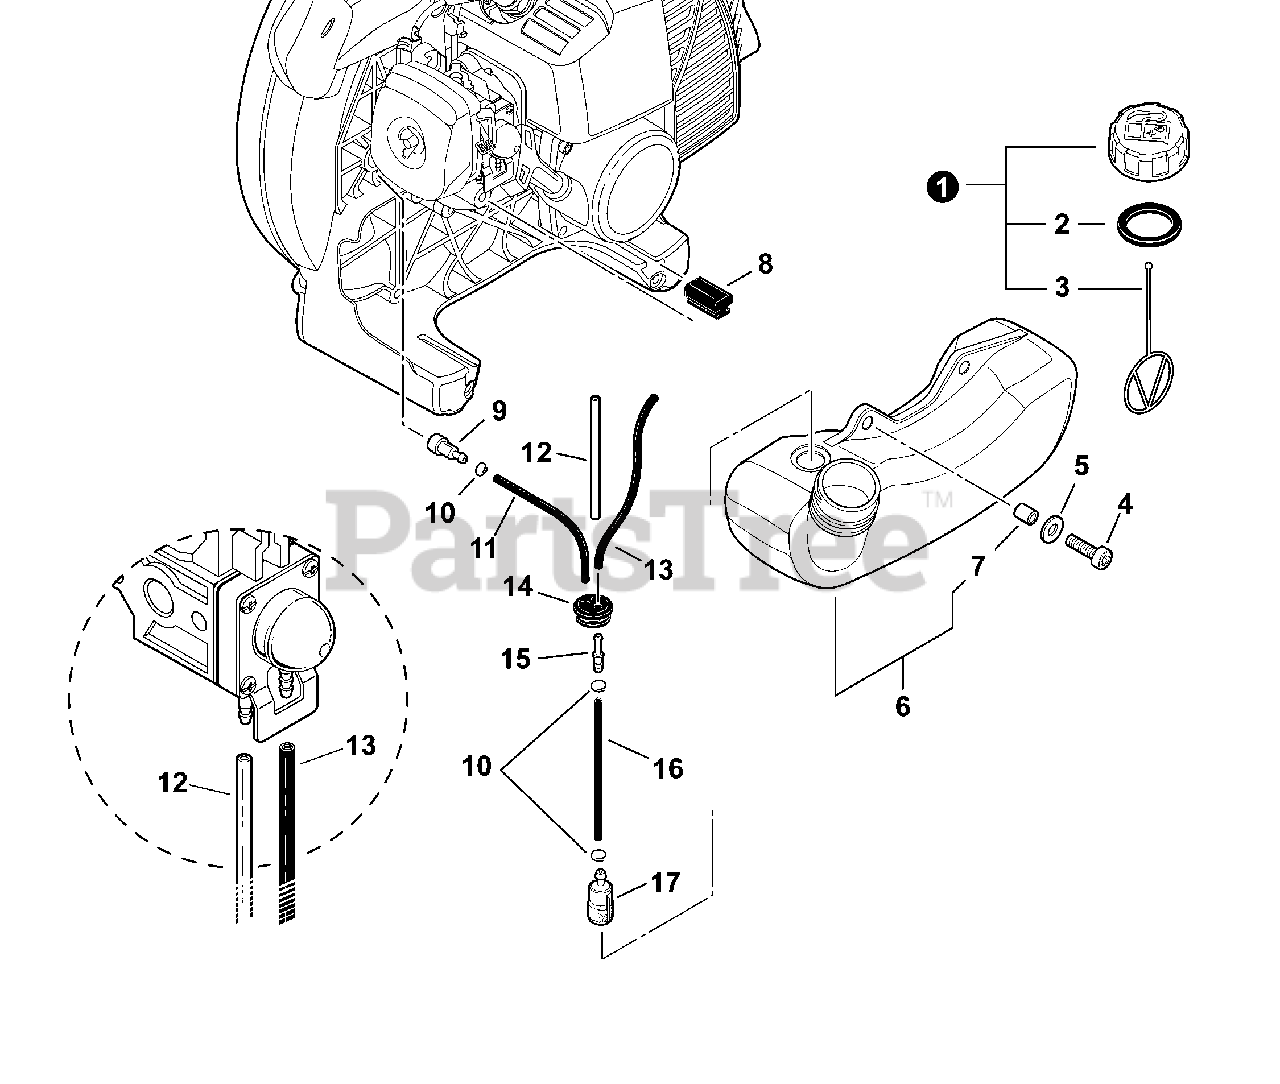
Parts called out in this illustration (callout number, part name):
1	CAP ASSY - ORANGE
2	CONNECTOR, CAP
3	GASKET, CAP
4	SCREW - 5×16
5	WASHER - 5
6	FUEL TANK ASSY
9	VENT, FUEL TANK
10	CLIP - 6
11	PIPE - 3×6×80 -- BLACK
12	PIPE - 3×6×85 -- CLEAR
13	PIPE - 3×5×78 -- BLACK
15	CONNECTOR, FUEL PIPE
16	PIPE - 3×5×130 -- BLACK
17	FILTER, FUEL
